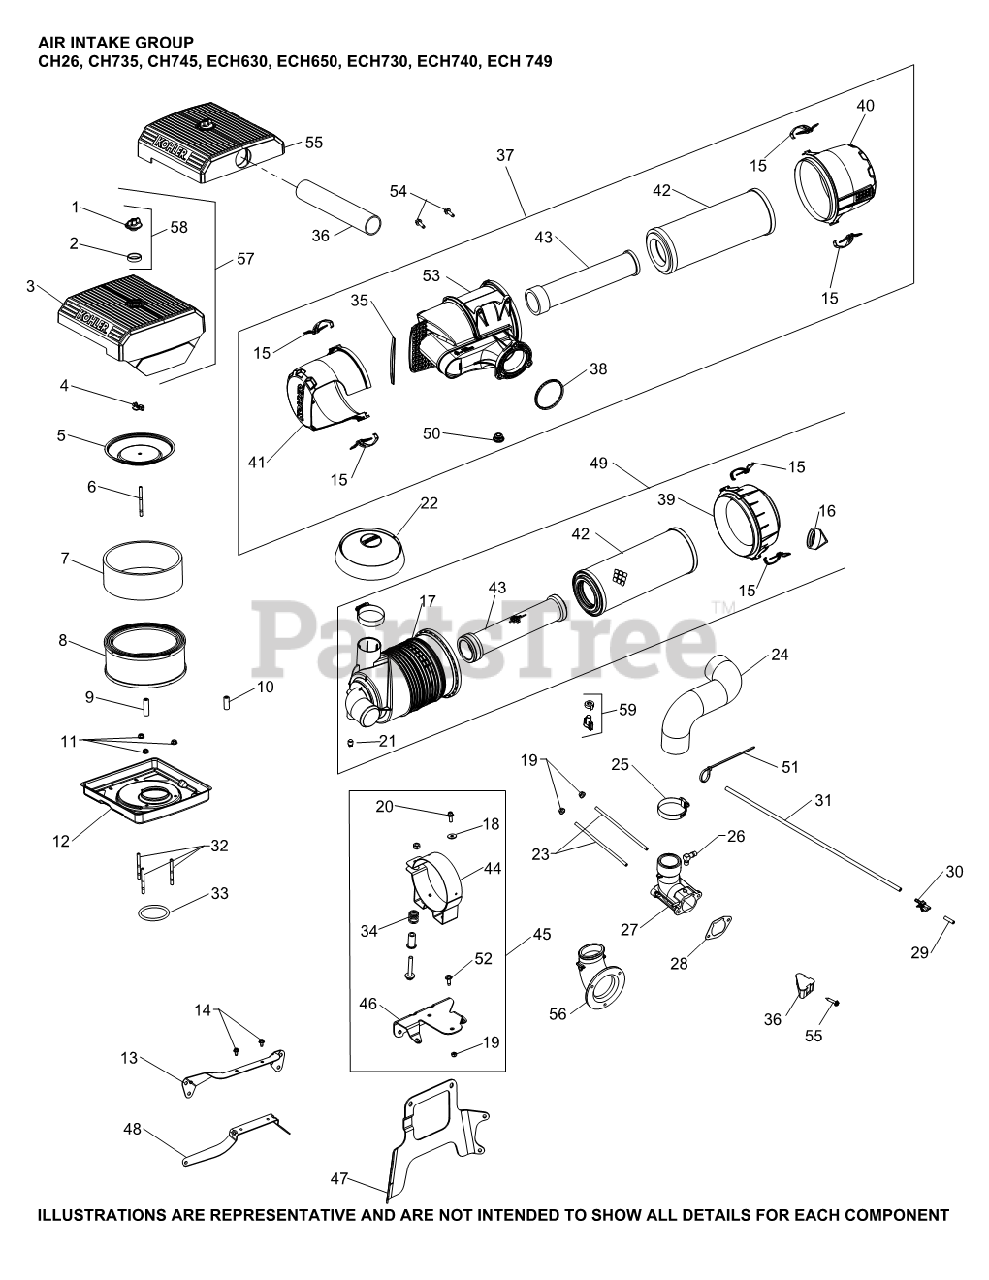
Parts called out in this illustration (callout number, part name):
1	KNOB, COVER
3	COVER, AIR CLEANER
4	NUT, WING
5	COVER, INNER AIR CLEANER
6	STUD, LOW PROFILE A/C
7	PRE-CLEANER (HIGH)
8	ELEMENT, AIR FILTER (HIGH) - Also available Retail Packaged 24 883 03-S1 Air Filter Kit
11	NUT, FLG M6X1.0
12	BASE, AIR CLEANER
13	BRACKET, AIR CLEANER BASE
14	SCREW, THREAD FORMING
33	O-RING, AIR CLEANER BASE
57	KIT, AIR CLEANER COVER
58	KIT, KNOB W/SEAL
